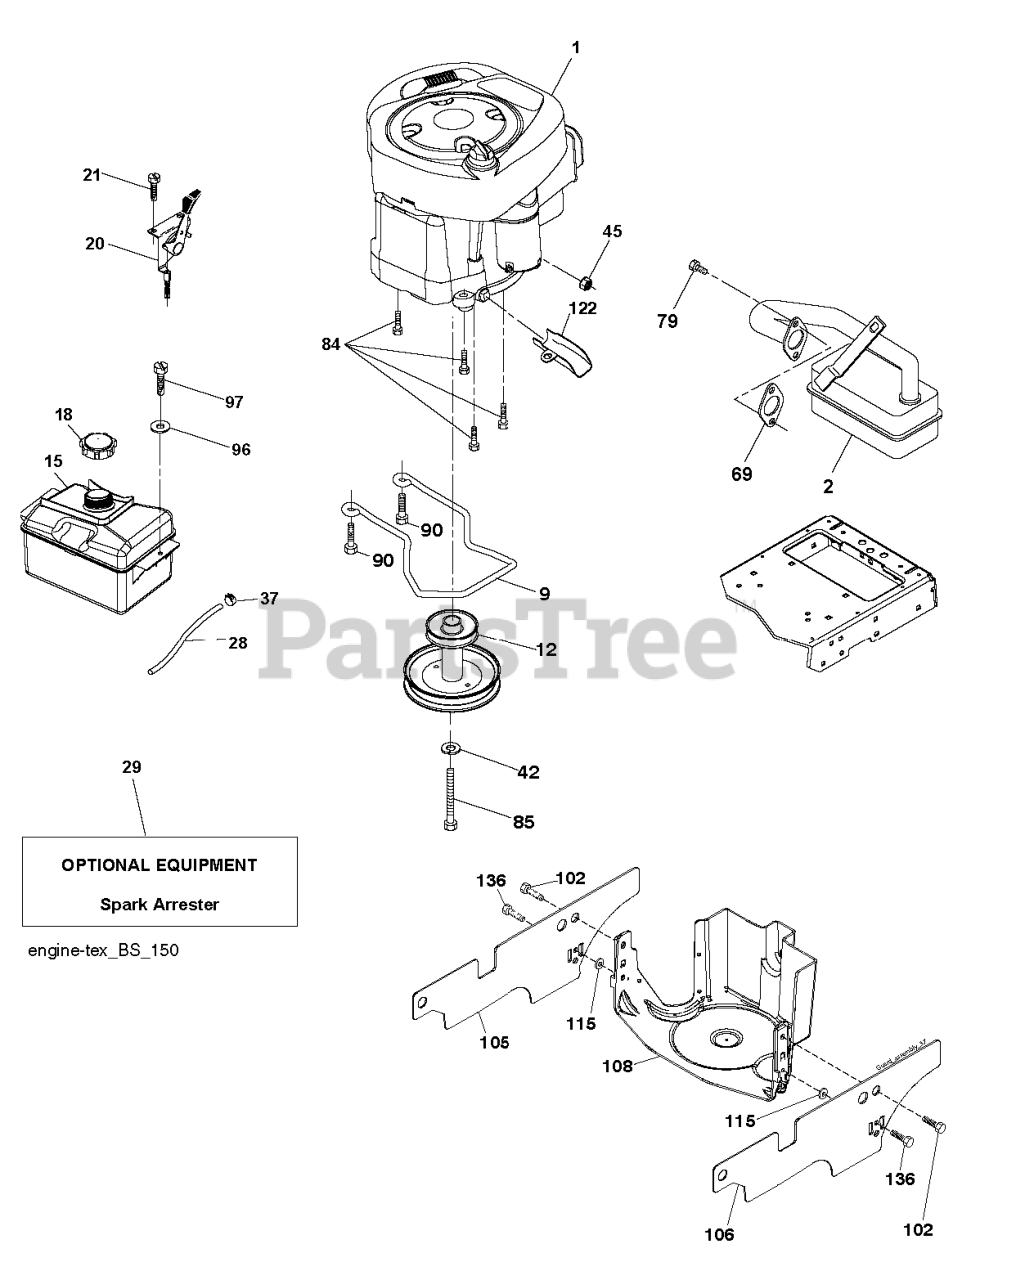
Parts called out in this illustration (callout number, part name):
2	MUFFLER.B&S.MODEL.21.11HP.OHV
9	KEEPER.BELT.ENG.3.25"2BOLT.PNT
12	PULLEY.ENGINE
15	FUEL.TANK.ASM.NON-EPA
18	CAP ASM.FUEL.2.25"FR.
20	THROTTLE.COBRA.21".RSTART.BLK
28	LINE.FUEL.20
29	KIT.SPARK ARRESTOR 794945 B&S
37	HOSE CLAMP
69	REPL BY 532 27 22-93
84	SCREW.3/8-16
85	BOLT.HEX.7/16-20X4.GR5.1.5BLUE
90	SCREW 3/8-16X1
97	SCREW HEXWSHR 1/4-20X3/4
102	SCREW
105	SHIELD.SIDE.LH.3842"TEX FRN.BK
106	SHIELD.SIDE.LH.3842"TEX FRN.BK
108	COVER ENGINE PULLEY COVER WITH
122	EXTENSION DRAIN OIL
